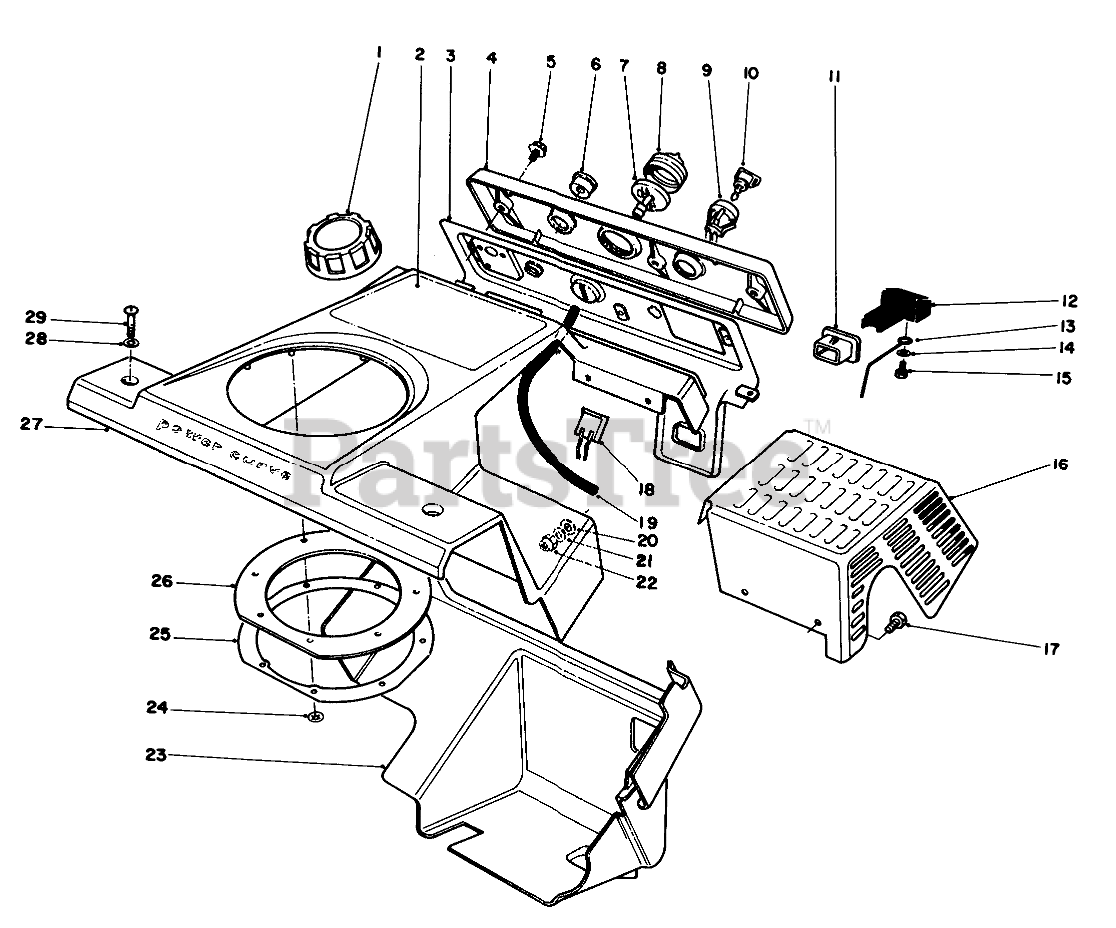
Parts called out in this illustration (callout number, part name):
1	CAP-FUEL ASM
2	DECAL - CCR 2000
3	Control Panel Assembly (Incl. Ref. #6-8 & 11)
4	CONTROL NAMEPLATE
5	SCREW
6	GUIDE-ROPE, STARTER
7	BODY-PRIMER
8	BULB-PRIMER
9	SWITCH
10	KEY-IGNITION
11	FITTING
12	CONTROL-CHOKE
13	Linkage-Choke
14	Washer
15	#8 X .625" PHILPS PAN H
16	Wa-Shield
17	SCREW-SHH
18	CONNECTOR-BODY
19	PRIMER HOSE
20	WASHER
21	WASHER-FLAT
22	NUT-LOCK, SIDE
23	Shroud-Lower
24	PALNUT
25	Retainer-Chute Seal
26	SEAL-CHUTE
27	Upper Shroud Assembly (Incl. Ref. #2 & 24-26)
28	WASHER-FLAT
29	SCREW-PPH
